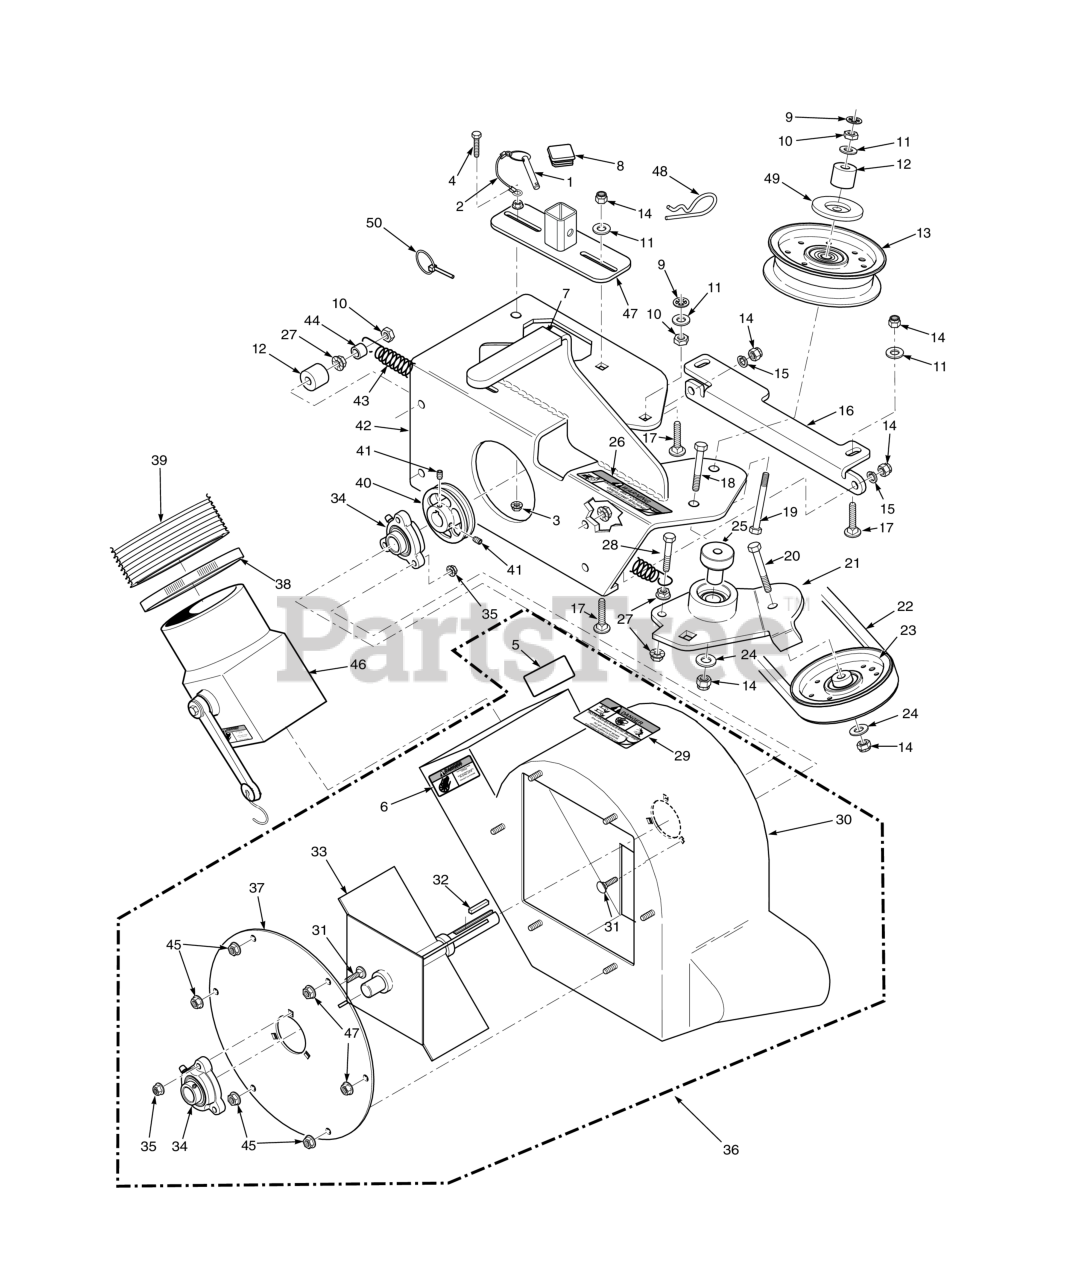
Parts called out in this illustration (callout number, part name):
1	Pin, Ring 1/2 x 2-1/4"
2	Lanyard, Deck Height Pin
3	NUT, 1/4-20 SERRATED FLANGE HEX HEAD
4	SERR. FLG. HEX HEAD CAPSCREW, 5/16-18 X 3/4
5	Decal, Blower
6	Decal, Rotating Blower
7	Grip, Deck Latch Lever
8	Cap, Square Vinyl
9	Nut, Push-On - 3/8" Dia.
10	Bolt, Hex Head 3/8-16 x 1" Ser. Flg.
11	Flatwasher, 3/8" Special (.391 x .938 x .105)
12	SPACER, J-PULL ROD
13	Pulley, Idler 3-1/2" Dia. - 52"
14	HEX NUT, ELASTIC STOP LOCK, 3/8-16
15	Lockwasher, 3/8" Spring, Kawasaki FX / FT & FT-EFI / B&S 32BV
16	Plate, Catcher Mounting
17	Bolt, RDHD Carr. 3/8-16 x 1-1/2 (52" & 61")
18	Bolt, Hex Head 3/8-16 x 3" - 52"
19	Bolt, Hex Head 3/8-16 x 3-1/2" Full Thread
20	Bolt, Hex Head 3/8-16 x 1-3/4" (Kohler EFI)
21	Idler Arm Assembly - 52"
22	Belt, GC-SCZ-48V / STCII-48V
23	Pulley, 3-1/2" O.D., GC-STT 52"
24	Flatwasher, 3/8 (.391 x .938 x .105 HD) Grade 8
25	Pivot, Idler Long - 52"
26	Decal, Warning - Belt Cover
27	NUT, 3/8-16 SERRATED FLANGE HEX HEAD
28	Bolt, Hex Head 3/8-16 x 1-1/2" Grade 8 Black
29	Decal, Danger
30	Blower Housing Weldment w/Decals
31	Bolt, 5/16-18 x .75 RHSN Carriage
32	KEY 1/4 X 1/4 X 1 1/2"(FOR 1" CRANKSHAFT
33	Fan Weldment
34	Bearing Assembly
35	HEX NUT, ELASTIC STOP LOCK, 5/16-18
36	Blower Housing Assembly, GC-STT
37	COVER, BLOWER HOUSING
38	Clamp, 8-5/8" Max Dia. (61")
39	Hose, 8.00" Dia. x 68" Long
40	Pulley, 4-3/4" O.D. - 1" Bore
41	Setscrew, Hex Socket Knurl Cup Pt. 5/16 - 18 (nylock)
42	Frame, Blower Mount
43	Spring, Helper (61" Cutter Deck Only)
44	Spacer, Deck Assist
45	Nut, Serrated Flange 5/16-18 (Right Front Engine Mounting, Briggs and Kohler Only)
46	Adapter, Blower GC-STC,
47	Receiver Weldment, Mount Post - 52"
48	Hair Pin Cotter, .177" x 3-1/4"
49	Quick Pin, 5/16" Dia.
50	Quick Pin, 5/16" Dia.
